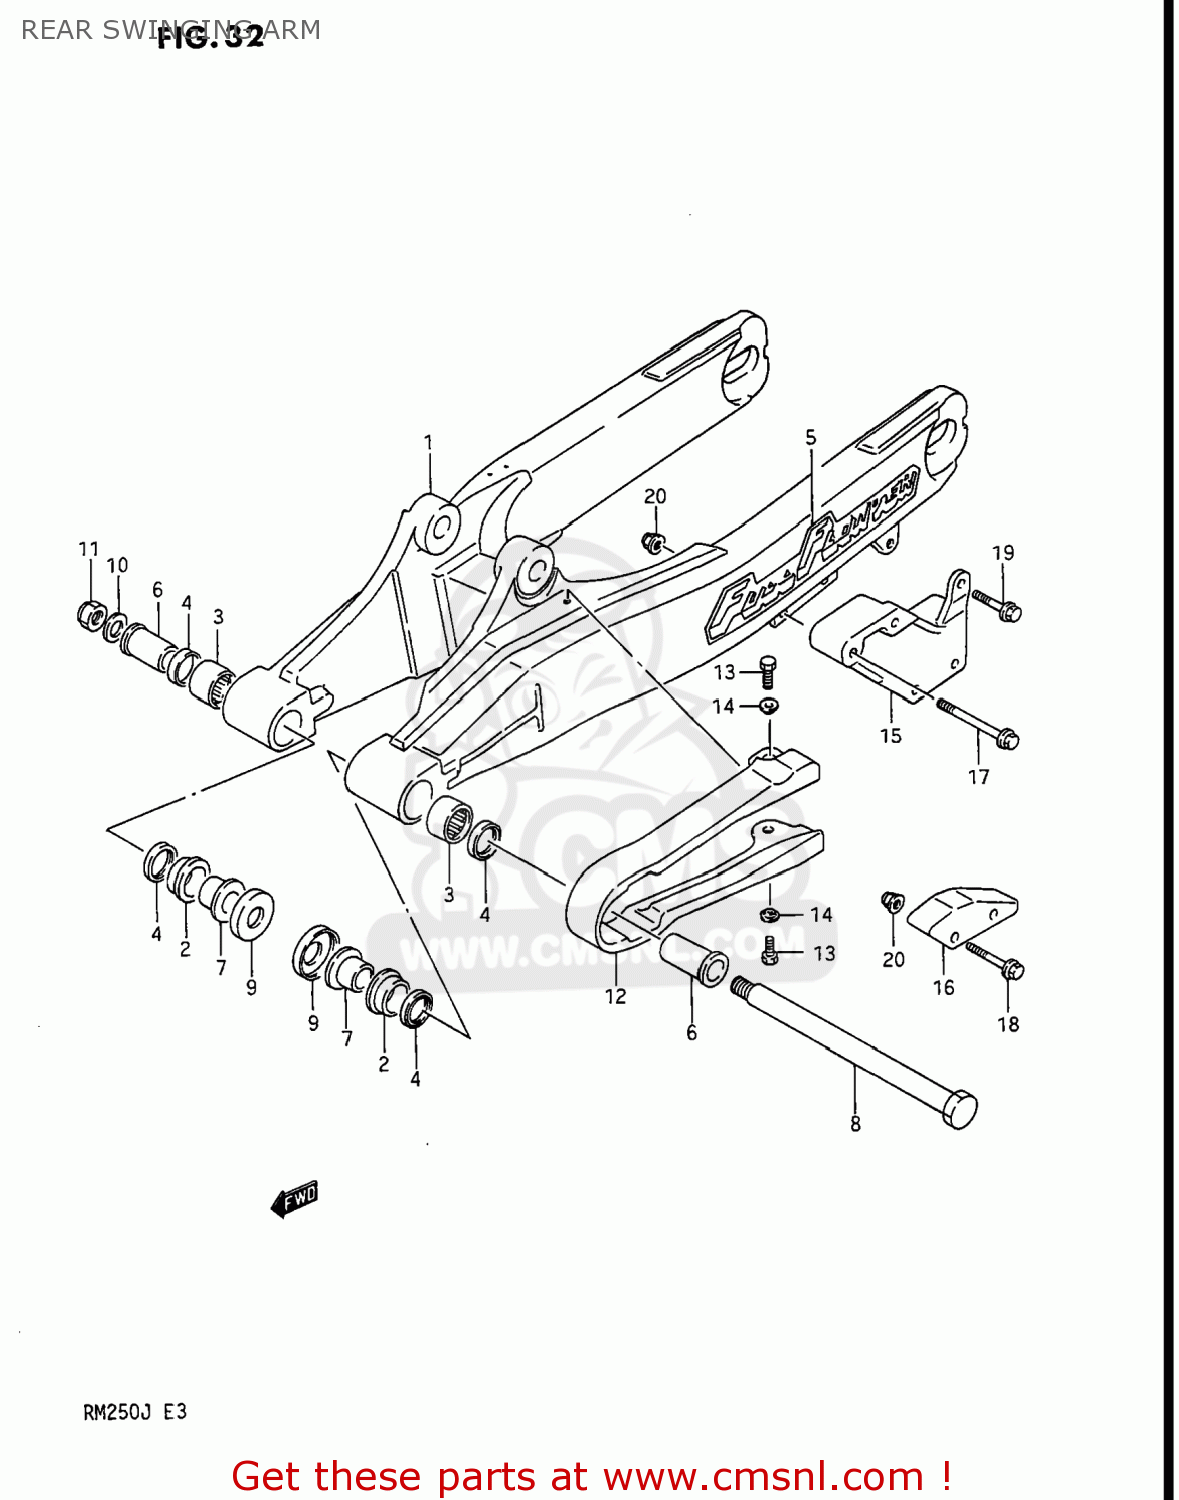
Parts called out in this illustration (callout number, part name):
1	SWING ARM ASSEMBLY,REAR
2	BUSHING,REAR SWING ARM PIVOT
3	BEARING(20X27X30)
4	OIL SEAL
5	LABEL (FRONT CARRIER WARNING)
6	SPACER,RR SWINGING ARM PIVOT
7	SPACER,RR SWGARM PIVOT INNER
8	SHAFT,RR SWINGINGARM PIVOT
9	COVER,RR SWGARM DUST SEAL
10	WASHER(14.5X29X2.3)
11	NUT
12	BUFFER,CHAIN TOUCH DEFENSE
13	BOLT
14	WASHER
15	GUIDE,CHAIN
16	DEFENSE,CHAIN GUIDE
17	BOLT
18	BOLT,UNDER
19	BOLT 6X20
20	NUT
